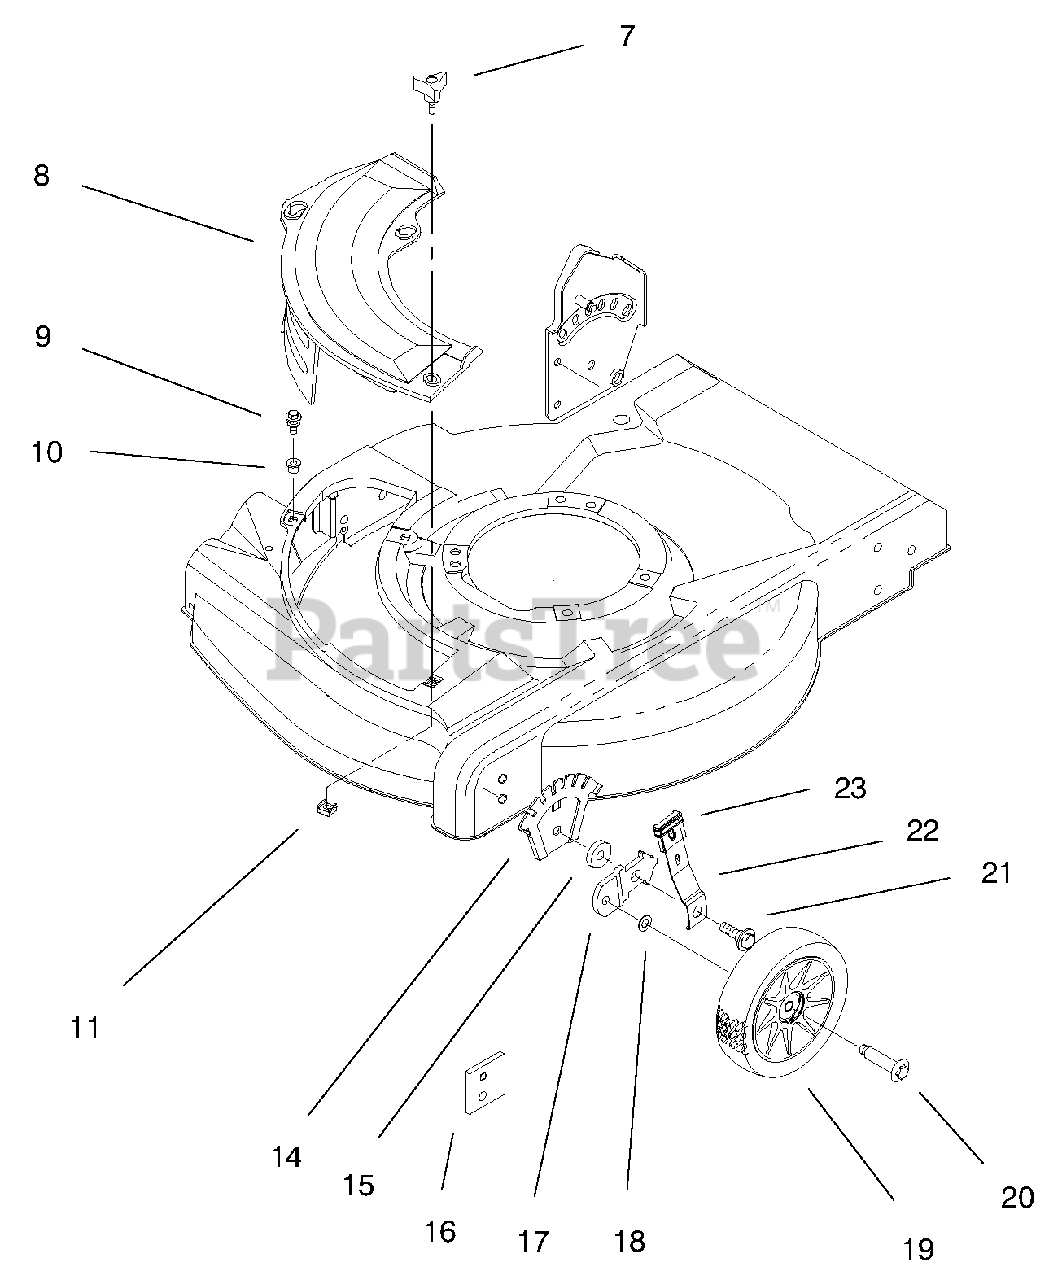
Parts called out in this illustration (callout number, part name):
7	Knob-Cover Plate
8	Plate-Mulch 21"
9	Screw-Sem Thr'd Form
10	Grommet-Plastic
11	Nut-Cage
14	Plate-Height Adjust
16	Plate-Baffle
17	Bracket-Wheel Height Adj.
19	Wheel & Tire Ass'y 6"
20	Bolt-Shoulder
21	Bolt-Shoulder Height Adj.
22	Spring Arm Ass'y-Front
23	Knob-Height Adjust
